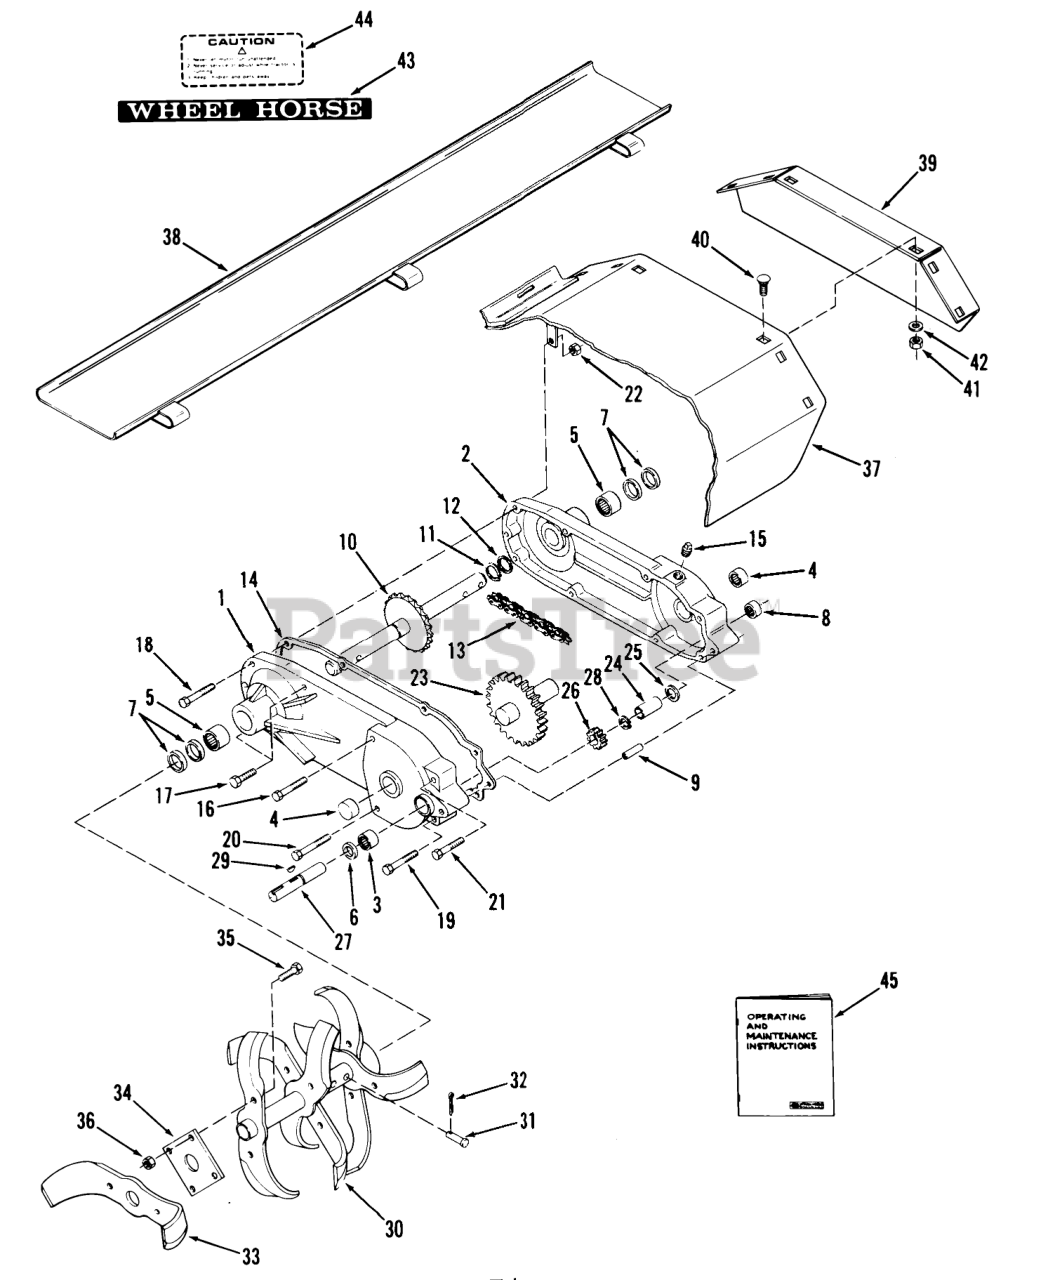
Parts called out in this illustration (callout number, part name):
1	R.H. Case (w/Bearings)
2	L.H. Case (w/Bearings)
3	BEARING-NEEDLE
4	BEARING-NEEDLE
5	BEARING-NEEDLE
6	SEAL-OIL
8	BEARING-NEEDLE
9	ROLL PIN 3/8 X 1
10	TINE SHAFT ASM
11	Snap Ring
12	WASHER
13	CHAIN
14	Gasket
15	SOLID PIPE PLUG
16	H H C S
17	Bolt
18	HHCS
19	BOLT
20	Hex Bolt
21	Bolt 3/8-16 x 4
22	NUT
23	GEAR AND SHAFT ASM
24	Spacer
25	WASHER-THRUST
26	GEAR-PINION
27	SHAFT-INPUT
28	RING-SNAP, EXTERNAL
29	Key
30	Tine R.H.
30	Tine L.H.
31	PIN-CLEVIS
33	R.H. Tine
33	L.H. Tine
34	Plate-Tine Mounting
35	H H C S
36	Nut
37	X-REF 92-6514-01
38	Rear Shield
39	Cover-End
40	CARRIAGE BOLT -4
41	Nut
42	WASHER 5/16 SAE
43	DECAL-WHEEL HORSE
44	Caution Decal
45	Operating and Maintenance Instructions
